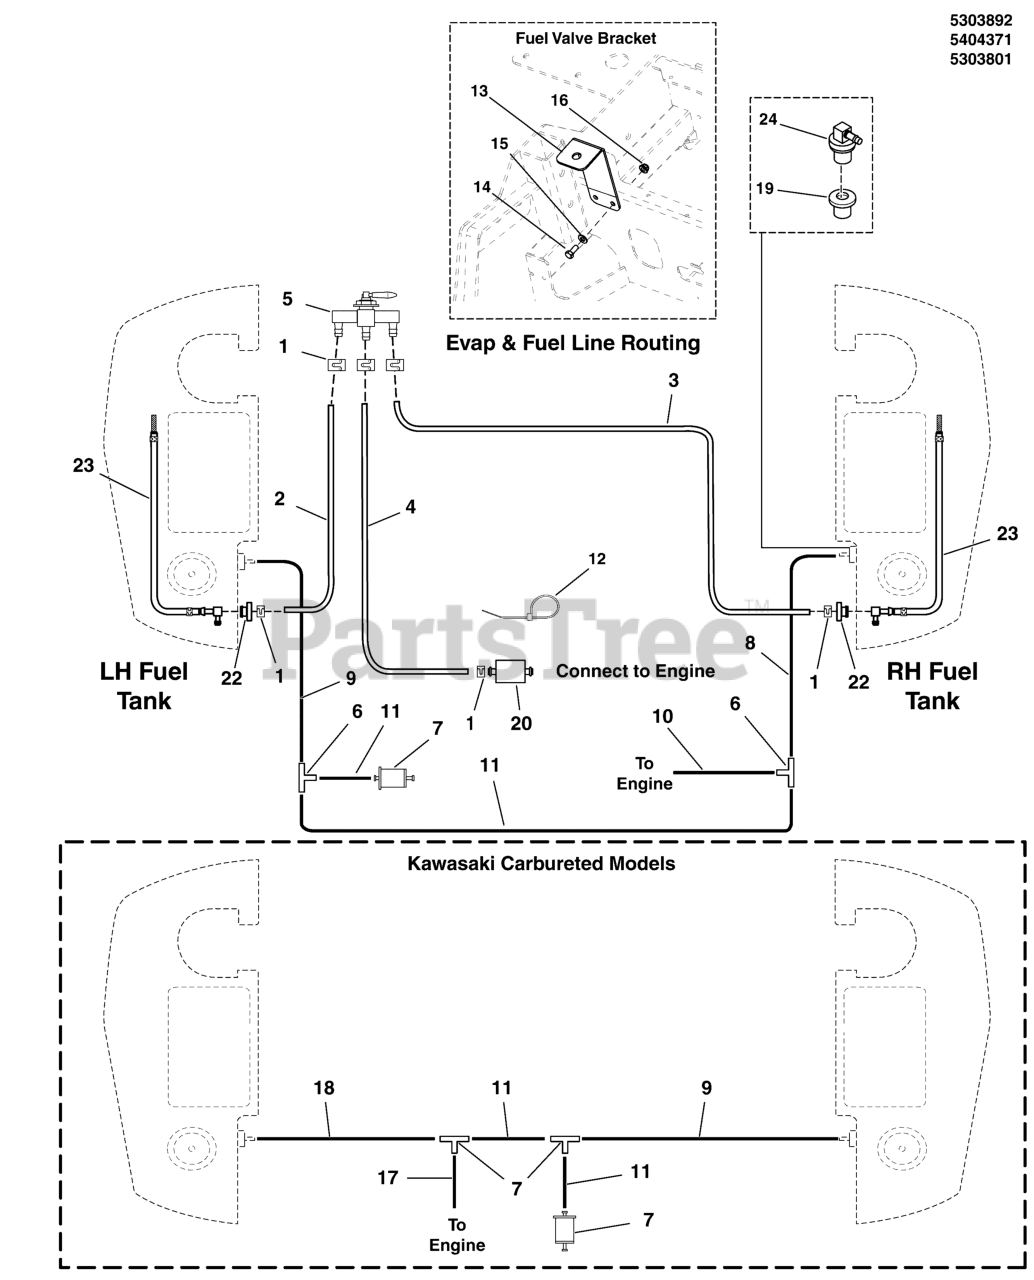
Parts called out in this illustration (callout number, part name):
1	CLAMP, Hose
2	HOSE, 1/4" FUEL, 14.50"
3	HOSE, 1/4" FUEL, 28.50"
4	HOSE, 1/4" FUEL, 12.50"
5	VALVE, FUEL STRAIGHT, OUTLET
6	FITTING, 3/16" TEE, BARB TYPE, HDPE
7	FILTER, FUEL
8	HOSE, VAPOR, 5MM ID, 18.00 LG
9	HOSE, VAPOR, 5MM ID, 28.50 LG
10	HOSE, VAPOR, 5MM ID, 12.00 LG
11	HOSE, VAPOR, 5MM ID, 3.00 LG
12	TIE, SELF-LOCKING, 12"
13	BRACKET, FUEL VALVE, IS2100 - BLK
14	BOLT, 5/16-18 X 3/4 GD5
15	WASHER, 5/16" SAE
16	NUT, 5/16-18 HEX NYLOCK FLANGE NUT
17	HOSE, VAPOR, 5MM ID, 33.00 LG
18	HOSE, VAPOR, 5MM ID, 14.00 LG
19	GROMMET (SV)
20	FUEL FILTER (SV)
22	BUSHING-FUEL TANK RED RUBBER
23	PICKUP TUBE ASSEMBLY, FUEL LINE (SV)
24	REMOTE VENT ASSEMBLY
